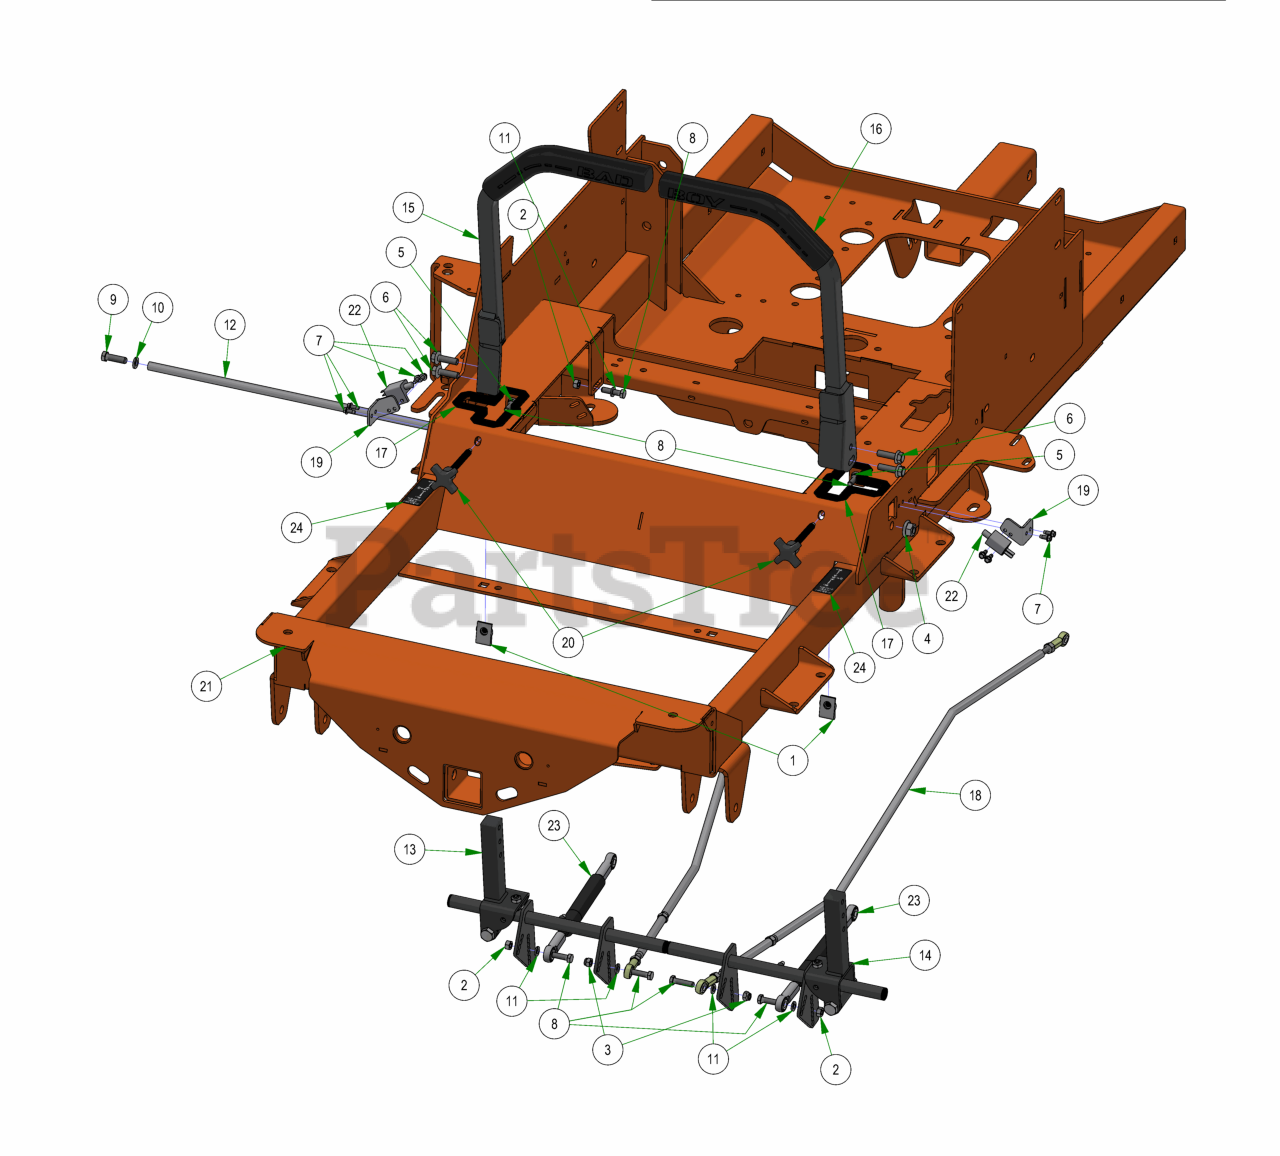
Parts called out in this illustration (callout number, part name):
1	Extruded Nut 3/8"-16 3/4" Hole Center With Patch
2	5/16-18 HEX NUT ZINC
3	5/16-18 NYL INS L/N ZC
4	1/2-13 NYLON INSERT FLANGE LOCKNUT ZINC
5	5/16-18 HEX SERRATED FLANGE NUT HARD/ZINC
6	3/8-16 X 1 1/4 HEX WASHER UNSLOT MACHINE SCREW ZINC GR5
7	12-24 X 1/2 HEX WASHER UNLSOT F TCS ZINC
8	5/16-18 X 1-1/4 HEX C/S (GR.5) ZC
9	3/8-16 X 1-1/4 HEX CAP SCREW (GR.5) ZINC
10	3/8 SPLIT LOCKWASHER ZINC
11	5/16 SPLIT LOCKWASHER ZINC
12	2019 Steering Actuator Rod
13	R Series Square Drive Arm Actuator RH Assembly
14	R Series Square Drive Arm Actuator LH Assembly
15	R Series Square Drive Arm RH Assembly
16	R Series Square Drive Arm LH Assembly
17	Snap-in Drive Arm Bushing
18	2019 Renegade Push Rod Assembly
19	2019 Arm Switch Bracket
20	Speed Limiting Knob 3/8-16X 3"
21	2022 Horizontal Diesel Frame
22	Safety Switch
23	2019 SROID Damper With Spherical Rod Ends
24	2018 LH/RH Steering Control Decal Roll
